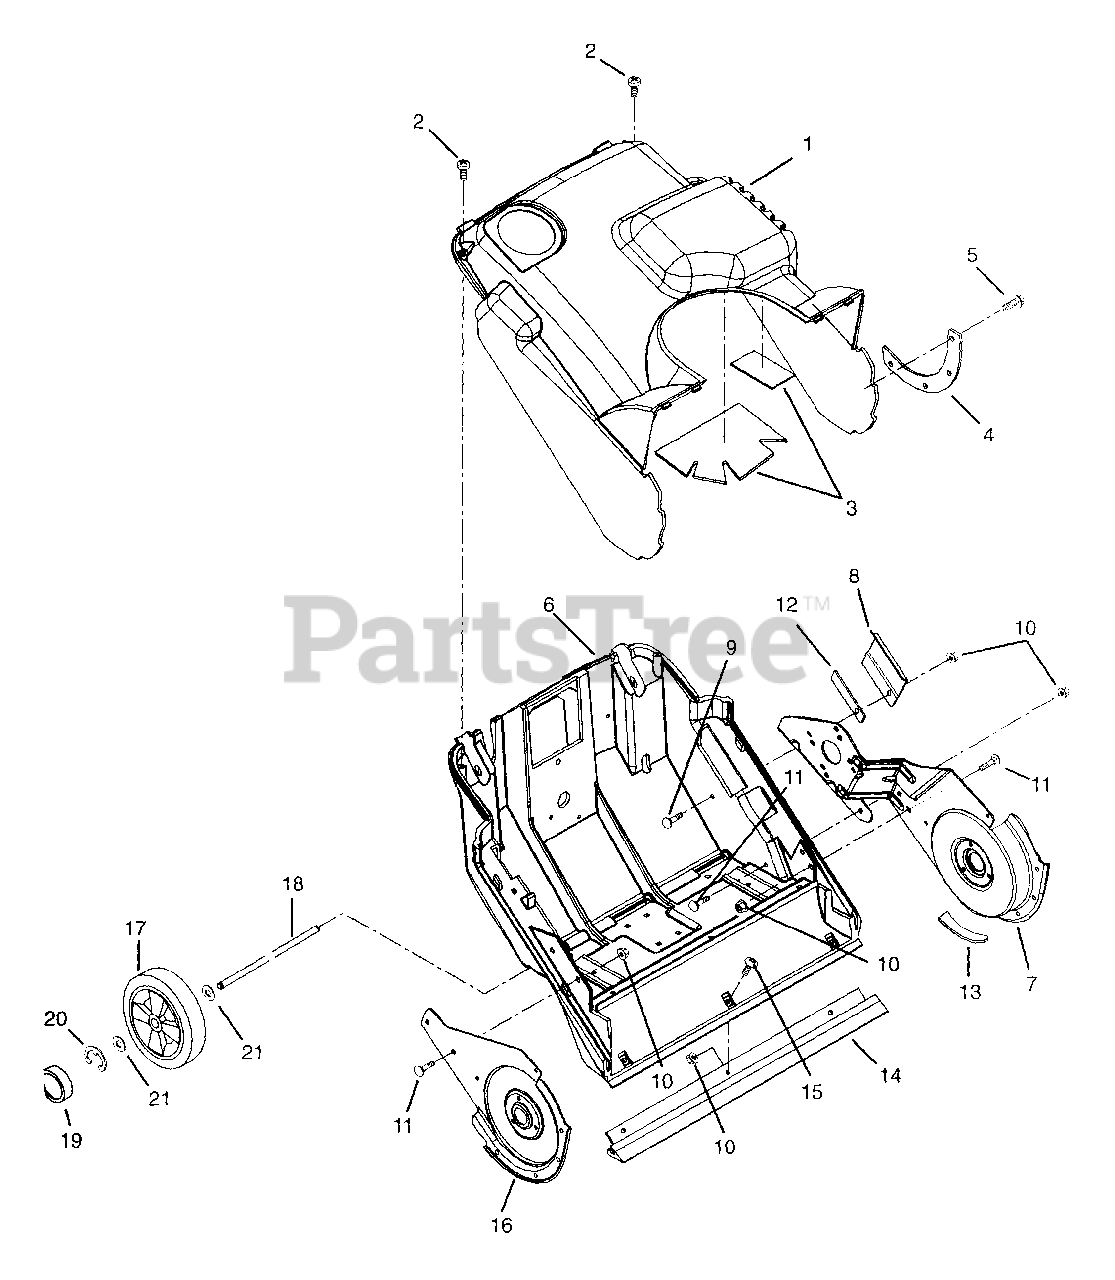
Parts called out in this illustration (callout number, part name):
1	COWL ASSEMBLY
2	SCR-SPEC-TAP #10X1.0
3	SHEET-HEAT REFLECTIVE 3X5
4	PLATE-COWL RETAINER
5	SCR-TAP 12-24X.50 HWH TR BLACK
6	CHASSIS, SS
7	SUPPORT-BRG,LH
8	DEFLECTOR, EXHAUST
9	@BLT-RDHDSQNK .25-20X1.00 G5YZ
10	NUT-LK-FLG .250-20 PL BLK
11	@BLT-RDHDSQNK .25-20X.75 G5YZ
12	PLATE, CABLE
13	TAPE-ADHESIVE BACKED FOAM 11.0
14	SCRAPER
15	SCR-MCH .25-20X.75 TXTR YWZC
16	SUPPORT-BRG,RH
17	T/WHL ASSY 7.0X1.5
19	CAP-HUB
20	RG-RTNG-EXT .375X.035
21	@WSHR-FL-STL.406X.812X.065 YWZ
